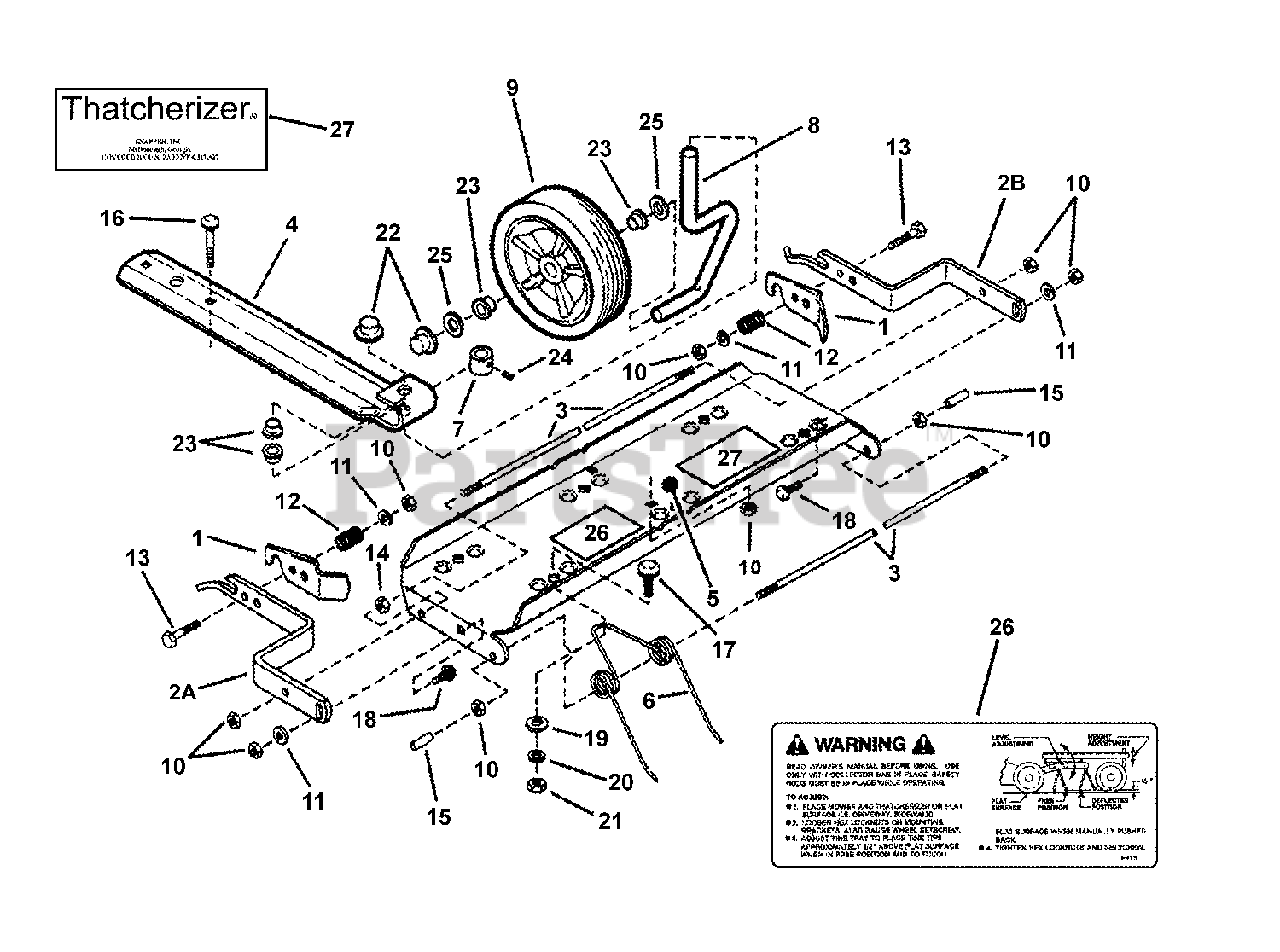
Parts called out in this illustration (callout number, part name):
1	LATCH, Frame Attachment
2A	BAR, Mount (Right Hand)
2B	BAR, Mount (Left Hand)
3	ROD, Tine
4	SUPPORT, Wheel
5	TRAY, Tine
6	KIT, Tine Thatching Spring
7	BUSHING, Wheel Adjuster
8	AXLE, Wheel
9	WHEEL, 7.00 x 1.50 Gage
10	NUT, 1/4-20 Hex Top Lock
11	WASHER, 1/4" Flat
12	SPRING, Compression
13	BOLT, 1/4-20 x 1-1/4" Hex, GR 5
14	NUT, 1/4-20 Hex, GR5
15	CAP, Vinyl
16	BOLT, 1/4-20 x 2-1/2" Square Neck Carriage
17	BOLT, 5/16-18 x 1" Square Neck Carriage, GR5
18	BOLT, 1/4-20 x 3/4" Square Neck Carriage, GR5
19	WASHER, Reinforcing
20	WASHER, 5/16" Split Lock
21	NUT, 5/16-18 Hex, GR5
22	NUT, 1/2" Push
23	BEARING, Nyliner
24	SCREW, 5/16-18 x 1/4" Set
25	WASHER, 1/2" Flat
26	DECAL, Adjustment
27	DECAL, Thatcherizer
